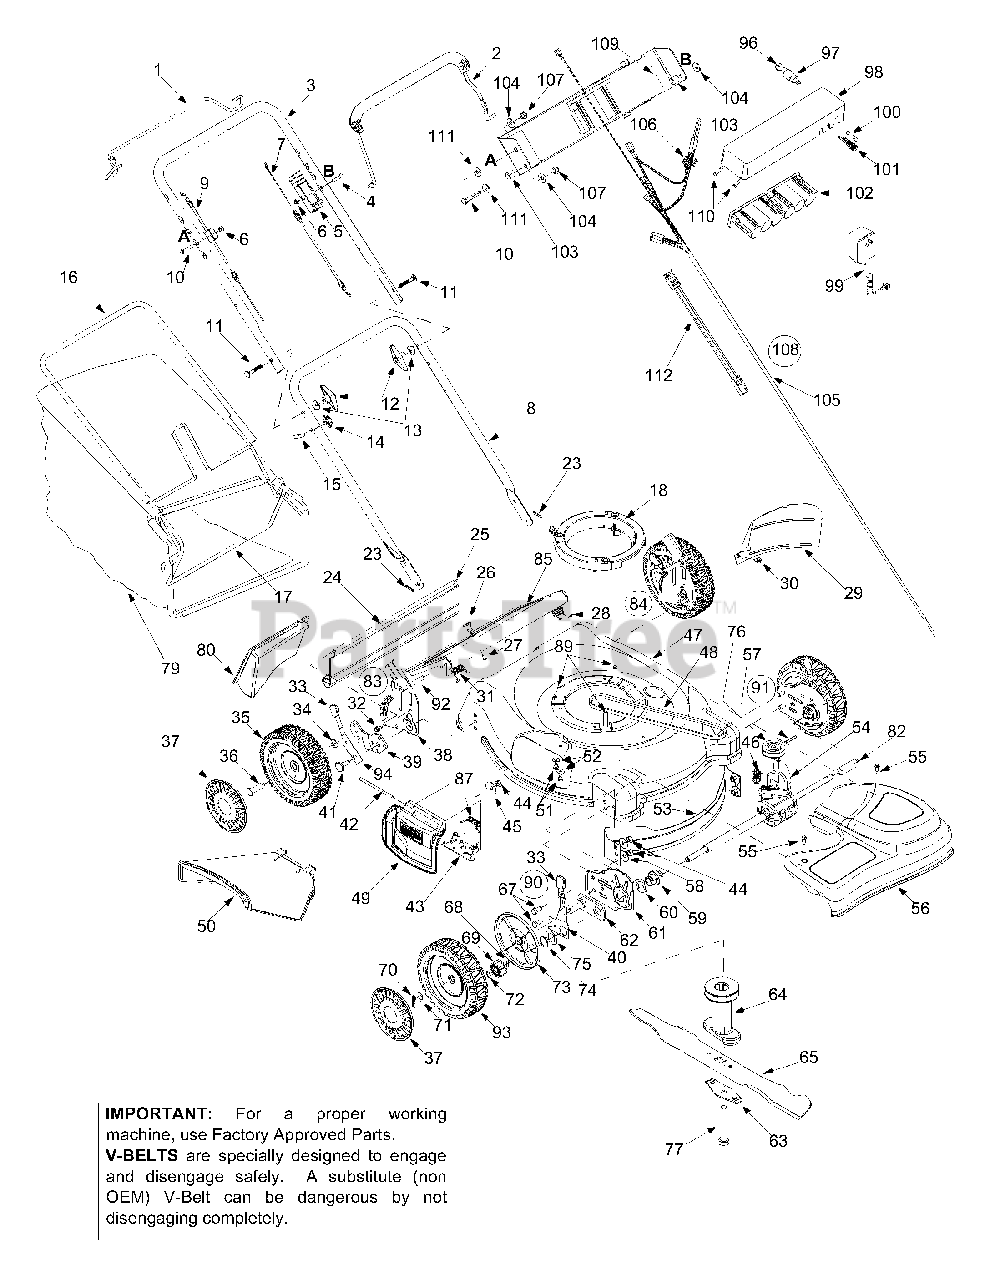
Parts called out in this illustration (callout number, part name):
5	Control Housing
6	Hex Lock Nut 1/4-20
7	Control Cable: 43"
9	Drive Cable
10	Hex Screw 1/4-20 x 1.5"
11	Carriage Bolt
12	Handle Knob
13	Saddle Washer
14	Wing Nut
15	Rope Guide
23	Hairpin Clip
24	Rear Trail Shield
25	Wire: Trail Shield
27	Scr. Tr. Mach. #10-24 x 0.380"
28	Torsion Spring LH
30	Scr. AB 1/4-14 x 0.625"
31	Torsion Spring RH
32	Hex Scr. w/ Wash. 1/4-14 x 0.62"
33	Knob
34	Bell Washer .375 x .870
35	Wheel: Rear
36	Shoulder Screw
37	Hubcap
38	Handle Bracket Assembly LH
38	Handle Bracket Assembly RH
39	Pivot Bar LH
39	Pivot Bar RH
40	Front Lever RH
40	Front Lever LH
41	Shoulder Screw
42	Hinge Pin
44	Lock Nut 3/8-16
46	Belt Tension Spring
49	Mulch Plug
50	Discharge Deflector SD
51	TT Screw 1/4-20 x 0.5"
52	Bell Washer 0.265" x 0.75"
55	Screw #12 x 0.457"
56	Front Drive Cover
57	Roll Pin
59	Bearing Support
60	Wave Washer
62	Pivot Plate Assembly
63	Blade Bell Support
64	Blade Adapter
65	Mulching Blade w/ Star: 21"
67	Hex Screw
68	Dowel Pin
69	Gear 14T RH
69	Gear 14T LH
70	Hairpin Clip
71	Flat Washer
72	Snap Ring
73	Wheel Dust Cap
74	Snap Ring
75	Washer DD 1.5" O.D.
76	Input Pulley
77	Hex Bolt
78	Bell Washer
79	Grass Bag
82	Slev. Spacer LH
82	Slev. Spacer RH
83	Height Adj. Assembly RH Compl.
84	Height Adj. Assembly LH Compl.
88	Cable Tie
89	TT Screw
90	Height Adj. Assembly RH Compl.
91	Height Adj. Assembly LH Compl.
92	Weld Pin
93	Wheel: Front
94	Spring Lever
96	Ignition Key
97	Key Switch
98	Battery Tray
99	Battery Charger
100	Fuse 7.5 Amp
101	Fuse Holder
102	Battery 12V
103	Spacer
104	Bell Washer
105	Harness: Electric Start
106	Plug
107	Lock Nut 1/4-20
108	Harness Assembly Compl.
111	Flat Washer
112	Harness Extension
